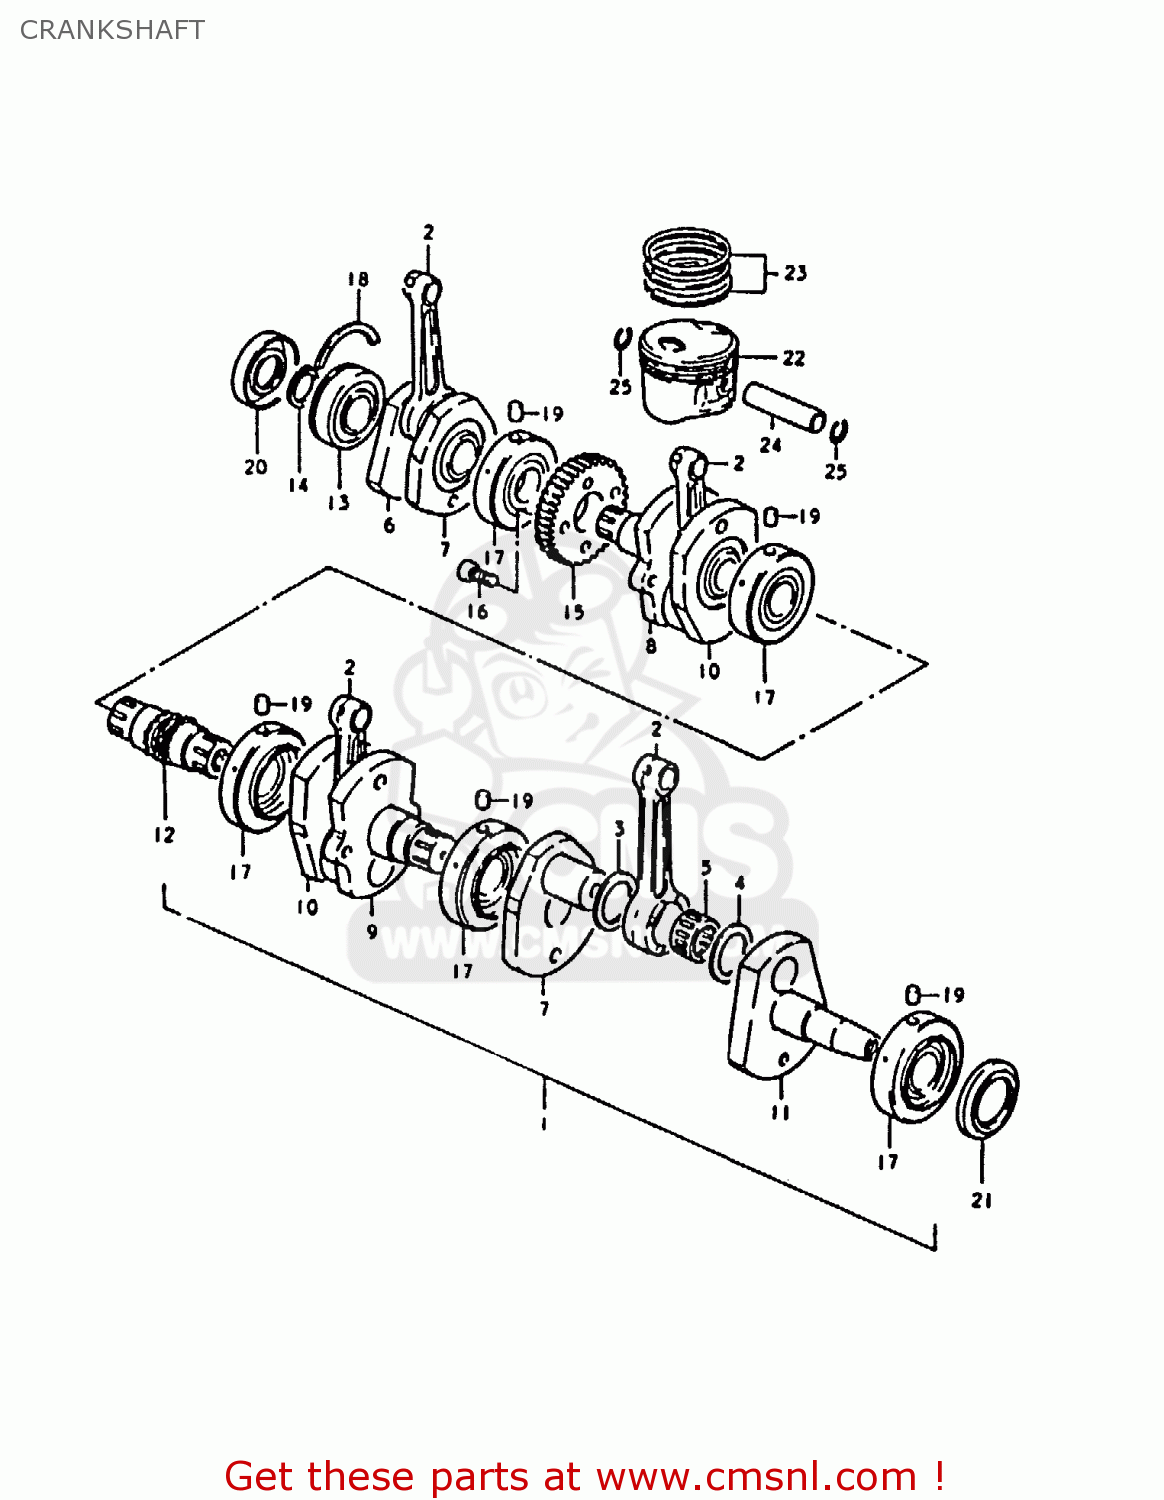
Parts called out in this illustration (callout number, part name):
1	CRANKSHAFT ASSEMBLY
2	ROD,CONNECTING
3	WASHER (29X48X2)
4	WASHER (29X48X1)
5	BEARING(29X39X20)
6	CRANKSHAFT
7	WEB,CRANK
8	CRANKSHAFT
9	CRANKSHAFT
10	WEB,CRANK,MIDDLE
11	CRANKSHAFT,LEFT
12	SHAFT,TIMING CHAIN DRIVE
13	BEARING(30X72X19)
14	CIRCLIP,30MM
15	GEAR,PRIMARY DRIVE
16	BOLT
17	BEARING
18	C RING
19	PIN
20	SEAL,OIL(30X72X11)
21	SEAL,OIL(47.3X60X6.5)
22	PISTON
23	RING SET,PISTON
24	PIN,PISTON (18MM)
25	CIRCLIP,PISTON PIN
